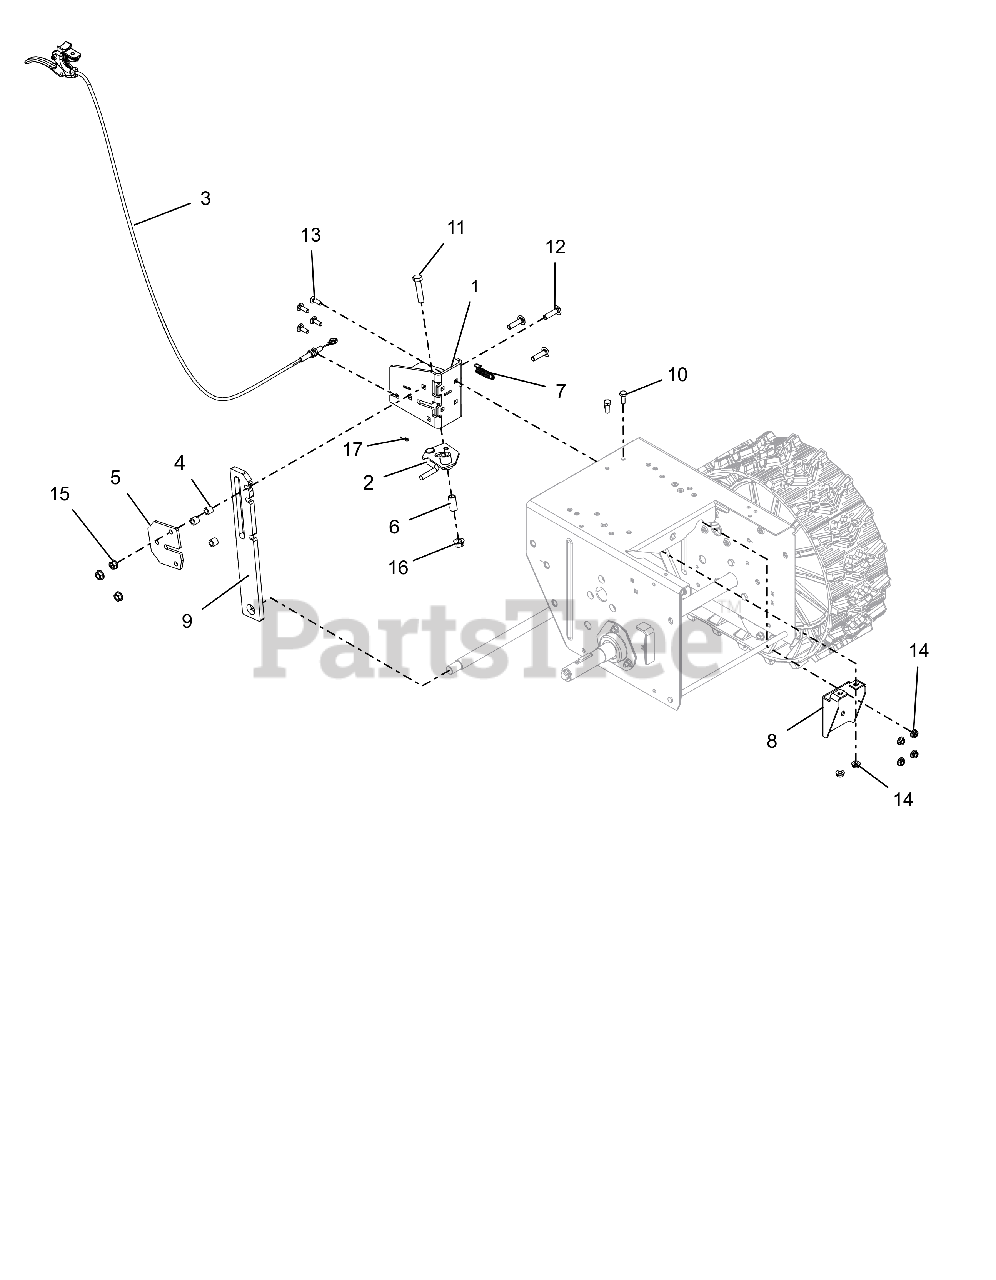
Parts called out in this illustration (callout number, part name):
1	BRACKET,HEIGHT ADJUSTER-DELUXE
2	LOCK,HEIGHT ADJUSTER TRIGGER
3	CABLE, TRACK REMOTE
4	SPACER .50 X .32 X .42
5	PLATE, HEIGHT ADJUSTER
6	BSHG-SLV .385X.500X1.045
7	SPRING-EXT .047 X .438 X 1.85
8	BRACKET, REINFORCEMENT
9	ADJUSTER, HEIGHT-BWT
10	@BLT-HEX .25-20X.75 GR5 YWZC
11	@BLT-HEX .38-16X1.75 GR5 YWZC
12	@BLT-RHDSHSQNK.31-18X1.25 G5YZ
13	@BLT-RDHDSQNK .25-20X.75 G5YZ
14	@NUT-LK-CTR-FLG .25-20 YWZC
15	@NUT-LK-TOP-FLG .31-18 YWZC
16	NUT-LK-CTR-FLG .38-16 YWZC
17	PIN-HAIR INT .06X.18X.77
